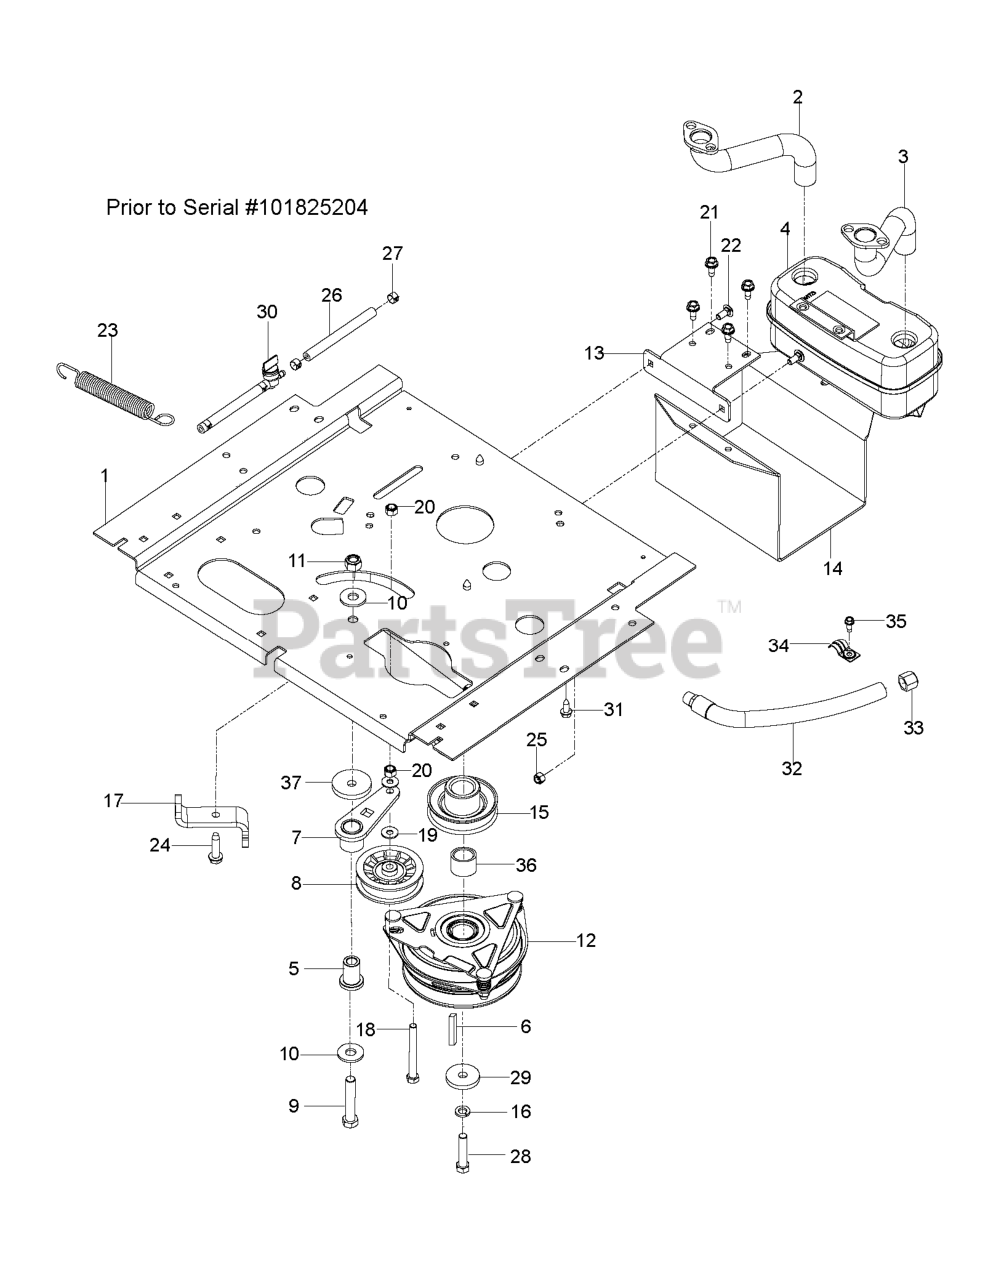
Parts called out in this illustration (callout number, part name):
1	PLATE, ENGINE WIDE, BLACK
2	RP.PIPE-EXHAUST LH
3	RP.PIPE-EXHAUST RH
4	MUFFLER ASM TWIN
5	PIVOT, IDLER
6	KEY, 1/4 SQ X 1 1/4
7	RP.IDLER ARM WELDMENT
8	PULLEY, IDLER RAKE & ZTR
9	HCS 1/2C X 2 3/4
10	WASH USS FLAT 1/2
11	NUT 1/2-13 HEX NYLOC ZD
12	CLUTCH, 150 FT/LBS
13	BRACKET, MUFFLER, BLACK
14	GUARD, MUFFLER, BLACK
15	PULLEY, DRIVE
16	WASHER 7/16 LOCK
17	STOP, CLUTCH BLK
18	HCS 3/8-16X3 1/2 GR5
19	WASHER 5/16 FLAT
20	NUT 3/8-16 NYLOC
21	BOLT 5/16-18 X 3/4
22	BOLT 5/16C X 3/4" CARRIAGE
23	SPRING, DECK DRIVE
24	BOLT 3/8-16 X 1 1/2 ZINC CLEAR
25	5/16-18 NYLOC FLANGE NUT
26	FUEL LINE 5"
27	HOSE CLAMP
28	HCS 7/16-20 X 2-3/4
29	SPINDLE WASHER
30	FUEL VALVE
31	HHFS 3/8-16 X 1.0 THD FORMING
32	OIL DRAIN HOSE
35	SCREW 1/4 X 5/8
37	HEAVY WASHER
